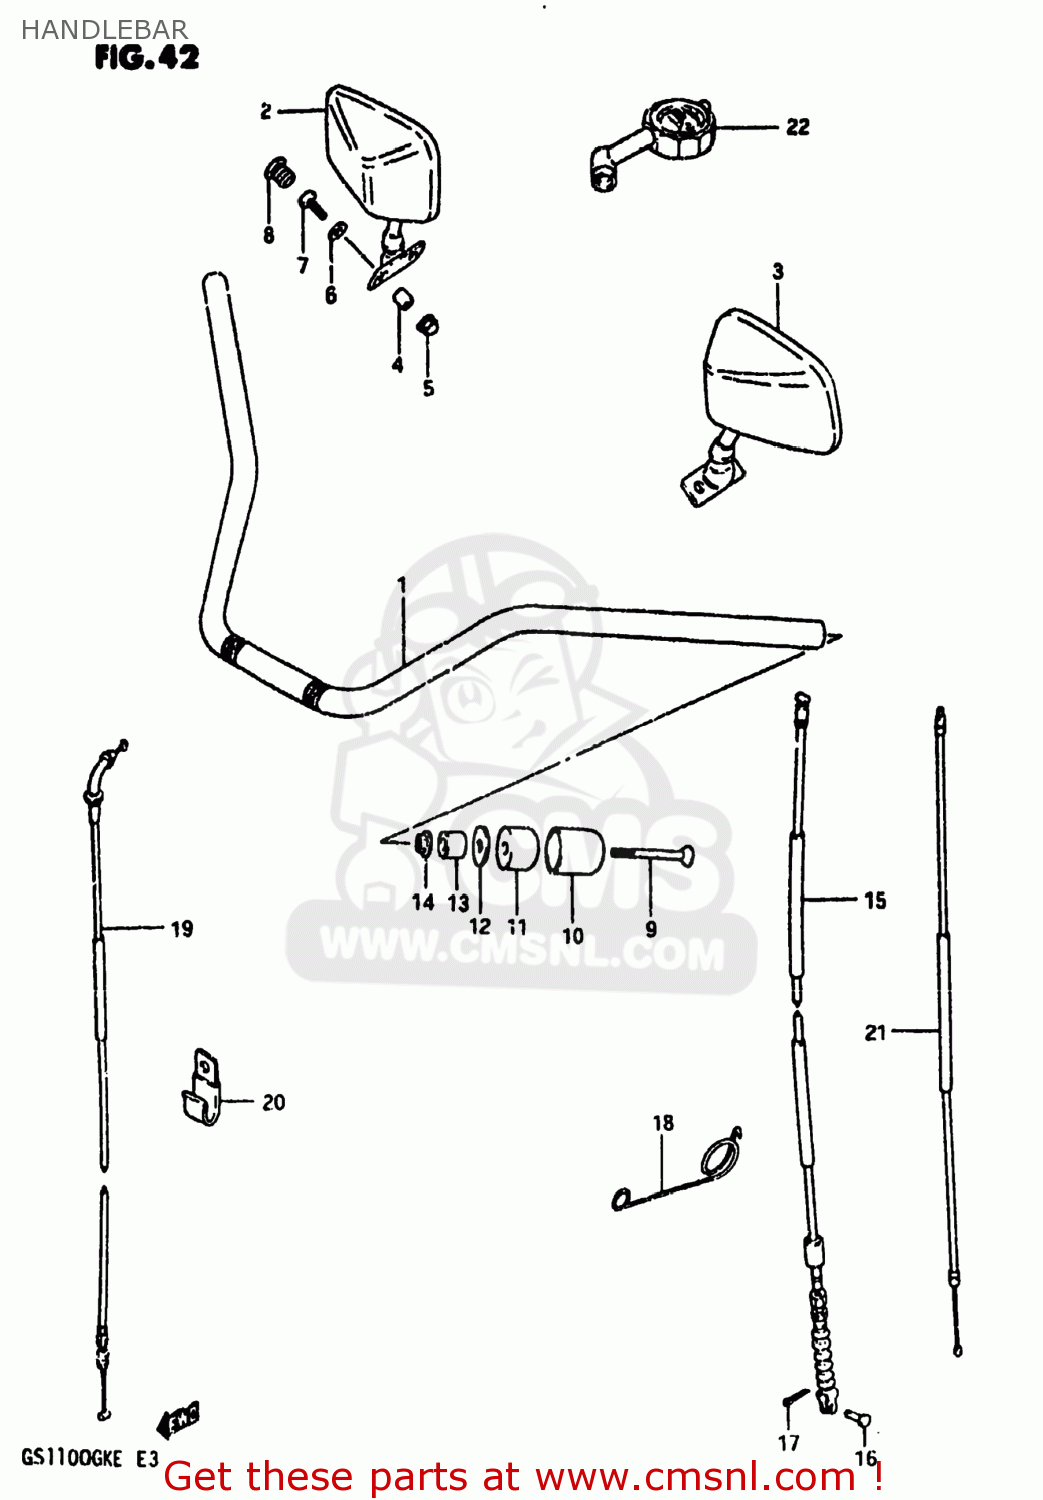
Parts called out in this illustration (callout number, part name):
1	HANDLEBAR
2	MIRROR ASSEMBLY,RIGHT
3	MIRROR ASSEMBLY,LEFT
4	SPACER(6.3X9.3X16.5)
5	NUT
6	WASHER
7	SCREW
8	CAP(OD:14)
9	SCREW
10	CAP,BALANCER
11	BALANCER,HANDLE
12	SPACER,BALANCER
13	EXPANDER,HANDLE BALANCER
14	NUT
15	CABLE ASSY,CLUTCH
16	PIN(L:15)
17	PIN
18	GUIDE,CLUTCH CABLE
19	CABLE ASSEMBLY,THROTTLE
20	CLAMP
21	CABLE ASSEMBLY,STARTER
22	GAUGE ASSY,AIR PRESSURE
